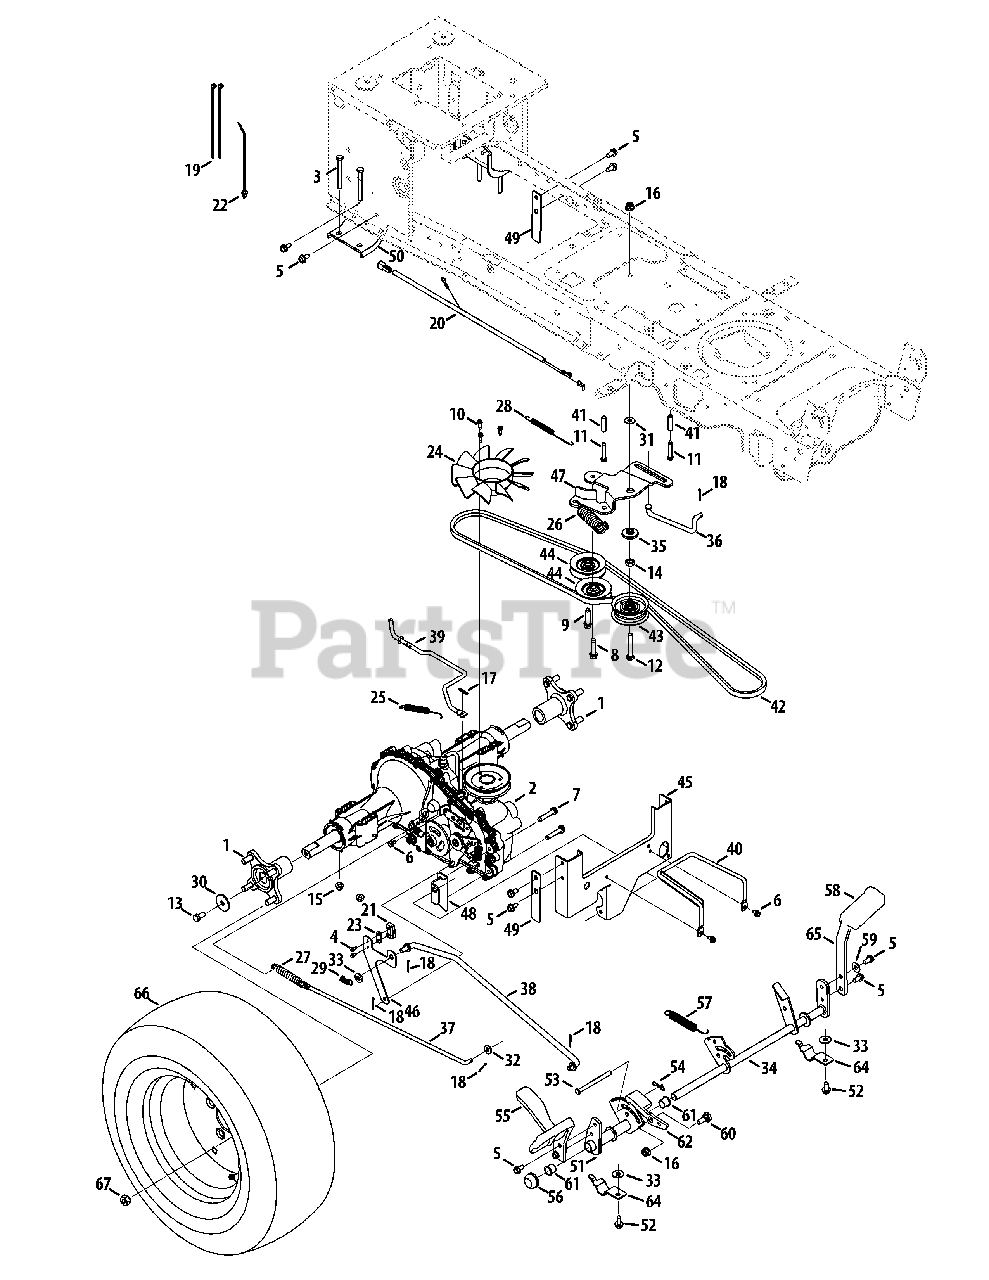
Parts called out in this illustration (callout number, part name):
1	Wheel Hub
2	Transmission
3	Hex Screw 5/16-18 X 3.00
4	Hex Wash HD AB S-Tapp Scr #8-.50
5	SCREW 5/16-18 x .750
6	Hex Wash S-Tapp Scr 1/4-20 x .50
7	Hex Wash TT-Tap Scr 5/16-18 x 1.75 Lg.
8	Hex L-Wash HD Scr 3/8-16 x 1.5
9	Hex L-Wash TT Scr. 3/8-16 x 1.88
10	Screw, #12-24 x .625
11	Hex Washer Hd. TT Screw 1/4-20 x 1.625
12	Hex Bolt 3/8-16 x 2.25" Lg.
13	Hex Cap Lock Screw 3/8-16 x .75 Gr. 5
14	Hex Jam Nut 7/16-20
15	Flange Locknut 5/16-18 Gr. F, Nylon
16	Flange Locknut 3/8-16 Gr. F Nylon
17	Int. Cotter Pin .072 x 1.13" Lg.
18	Cotter Pin 3/32 dia x 1.00 Lg.
19	Cable Tie
20	Jumper Harness
21	Short Spring Switch
22	Push Mount Tie
23	Insulator Nut Plate
25	Extension Spring .50 dia. x 5.0" Lg.
26	Extension Spring 1.0 dia. x 4.75" lg.
27	Extension Spring .59 dia. x 4.0" Lg.
28	Extension Spring .38 dia. x 5.6" Lg.
29	Extension Spring 3/8 dia. x 1.44" Lg.
30	Flat Washer .39 ID x 1.5 OD x .135
31	Flat Washer .385 x 1.0 x .03
32	Flat Washer .312 ID x .75 OD
33	Flat Washer .344 x 0.688 x .065
34	Shaft Ass'y
35	SHOULDER SPACER 1.375X.380X.183
36	Footpedal Bypass Rod
37	Brake Rod
38	Control Rod
39	Disengage Rod
40	Belt Keeper
41	Spacer .260 x .372 x 1.420
42	V-Belt, 4L x 77.0
43	Idler Pulley, Flat 2.75 OD
44	Idler Pulley V-Type x 3.06
45	Torque Bracket
46	Switch Bracket
47	Idler Bracket (Centre Double)
48	Deck Bracket
49	Plate Bracket
50	Axle Bracket
51	Hydro Petal Bracket Ass'y
52	Self-tapping Screw 5/16-18 x .625
53	Clevis Pin 5/16 x 3.985
54	Bow-Tie Cotter Pin
55	Control Pedal
56	Push Cap 5/8" Dia Rod
57	Extension Spring .63 dia. x 4.95
58	Brake Pedal Pad
59	Cupped Washer .345 ID x .88 OD x .060
60	Shoulder Screw .500 x .25
61	NYLINER BEARING
62	Cruise Latch
63	Pedal Strap Support Bracket
64	Pedal Strap Support Bracket
65	Brake Pedal Bracket
66	See Wheel Chart
67	Lug Nut 7/16-14
